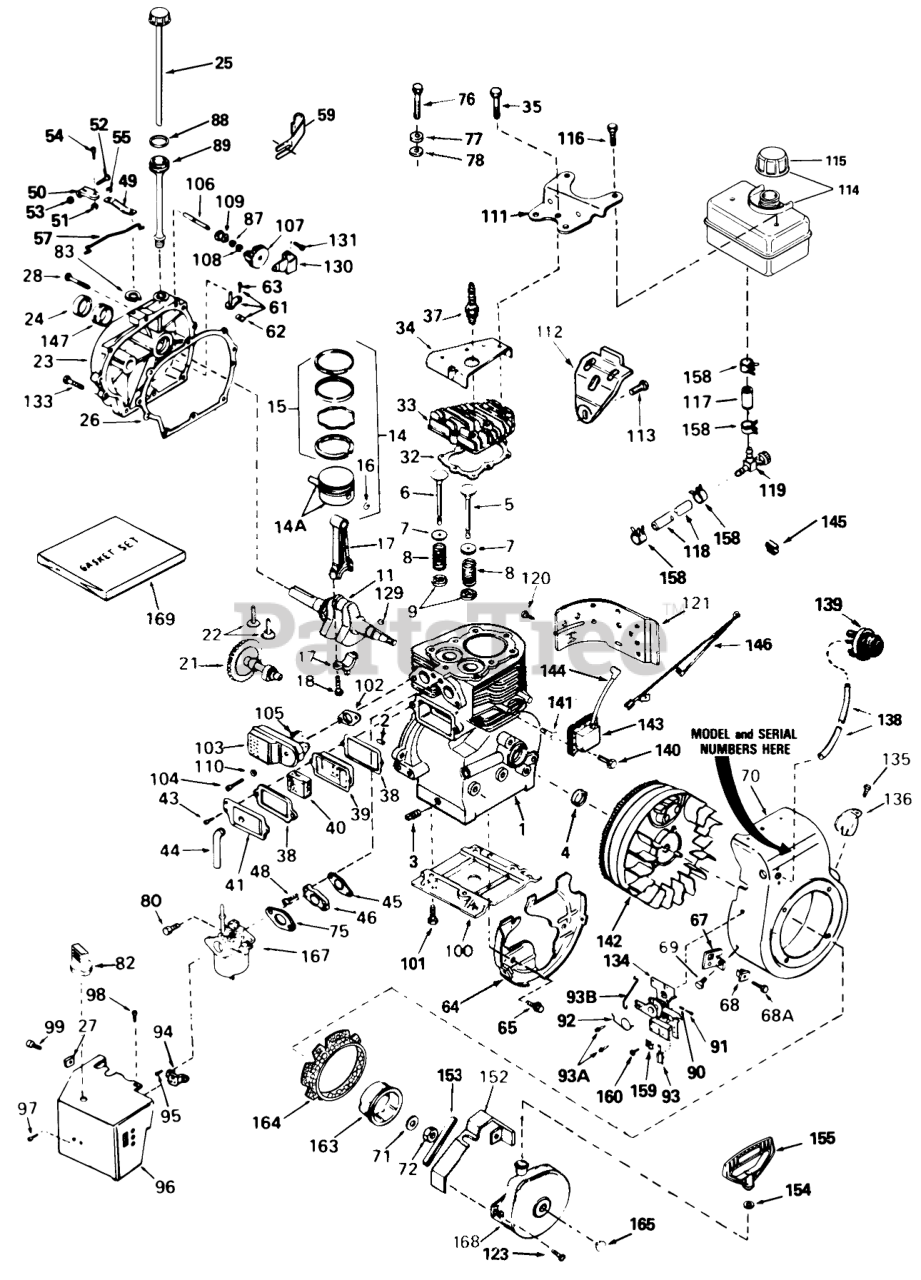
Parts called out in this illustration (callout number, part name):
1	Cylinder Assy. (Incl. Ref. #2, 3 & 4
2	Pin-Dowel
3	Plug-Drain, Oil (SQH 1/4-18)
4	Oil Seal
5	Valve, Intake (Std.) (Incl. Ref. #9)
5	Valve, Intake (1/32" oversize) (Incl. Ref. #9)
6	Valve, Exhaust (Std.) (Incl. Ref. #9)
6	Valve, Exhaust (1/32" oversize) (Incl. Ref. #9)
7	Cap-Spring, Valve
8	Spring-Valve
9	Keeper-Spring, Valve
11	Crankshaft Assembly (Incl. Ref. #12 & 13)
14	Piston, Pin & Ring Assy. (Std.) (Incl. Ref. #14A, 15 & 16)
14	Piston, Pin & Ring Assy. (.010 oversize) (Incl. Ref. #14A, 15 & 16)
14	Piston, Pin & Ring Assy. (.020 oversize) (Incl. Ref. #14A, 15 & 16)
14A	Piston & Pin Assy. (Std.) (Incl . Ref. #16)
14A	Piston & Pin Assy. (.010 oversize) (Incl. Ref. #16)
14A	Piston & Pin Assy. (.020 oversize) (Incl. Ref. #16)
15	Ring Set (Std.)
15	Ring Set (.020" OS)
15	Ring Set (.010" OS)
16	Ring-Retaining, Piston Pin
17	Rod Assy., Connecting (Incl. Ref. #18)
18	Bolt-Connecting Rod
21	55012A GIL SNWTHWR
22	Lifter-Valve
23	Cover, Cylinder (Incl. Ref. #24, 106 & 147)
24	Oil Seal
25	Dipstick
26	Gasket-Cover, Cylinder
27	Nut-U Type
28	Screw (1/4-20 x 1-1/4)
32	Gasket-Head, Cylinder
33	Head, Cylinder (Incl. 3 of No. 35)
34	Cover-Head, Cylinder
35	Screw (5/16-18 X 2-1/2)
37	Spark Plug-Resistor (R J19 L M)
38	Gasket-Breather
39	Body-Breather
40	Element-Breather
41	Cover-Valve
44	Tube-Breather
45	Gasket-Intake
46	Flange, Carburetor (Incl. Ref. #80)
49	Lever-Governor
50	Clamp-Lever, Governor
51	Nut-Lock
53	Nut-Lock
54	Screw
55	Washer-Lock
57	Governor Link
59	Clip-Tube, Fill
61	Rod Assy., Governor (Incl. Ref. #62 & 63)
62	Yoke-Governor
63	Screw (6-40x5/16)
64	Baffle-Blower Housing
65	Screw (1/4-20x19/32)
67	Bracket
68	Grommet
68A	Screw (8-32 x 3/8)
70	Housing, Blower (Incl. Ref. #135 & 136)
71	Washer-Belleville
72	Flywheel Nut
75	Gasket-Carburetor
76	Screw (5/16-18 X 2-1/2)
77	Washer-Belleville
78	Washer-Flat
80	Screw (T-30, 1/4-20 X 27-32)
82	Knob-Choke
83	Ring-Retaining
87	Washer-Flat
89	Tube-Fill, Oil
90	Spring-Compression
91	Screw
92	Spring-Throttle
93	Terminal
93A	Screw (10-32 x 1/2)
93B	Link-Throttle
94	Bracket-Choke
95	Screw (10-32 x 1/2)
96	Carburetor Cover
97	Screw (8-32 X 5/16)
98	Screw (10-32x1/2)
99	Screw (8-32 x 3/8)
100	Base Engine
102	Gasket Exhaust
103	Muffler
104	Screw (5/16-18 X 2)
106	Shaft-Governor
107	Gear Assy., Governor (Incl. Ref. #87)
108	Ring-Retaining
109	Spool-Governor
111	Plate, Fuel Tank Mounting
112	Bracket, Fuel Tank Mounting
113	Screw (1/4-20x19/32)
114	Tank, Fuel (Incl. Ref. #115)
115	Cap-Fuel
116	Screw (1/4-15x7/8)
117	Line-Fuel
118	Line-Fuel (8.62)
119	Valve-Shut Off
121	Extension-Blower Hsng.
129	Key-Flywheel
130	Bracket, Governor
131	Screw (10-24x1/2)
134	Control Assy., Remote Speed (Incl. Ref. #90 thru 93)
135	Screw (8-32 x 3/8)
138	Line-Primer
139	Primer-Asm
140	Screw
141	Stud
142	Flywheel
143	Solid State
144	Cover-Spark Plug
145	Clip-Wire
146	Ground Wire
147	Bushing-Crankshaft
152	Guard-Starter
153	Seal, Snowguard
155	Handle-Starter, Mitten Grip
158	Clamp-Line, Fuel
159	Conduit
160	Screw (10-32 x 3/8)
163	Cup-Starter
164	Screen-Starter
165	Plug Starter
167	Carburetor (Incl. Ref. #75)
168	Starter-Rewind
169	Gasket Set (Incl. Items Marked )
